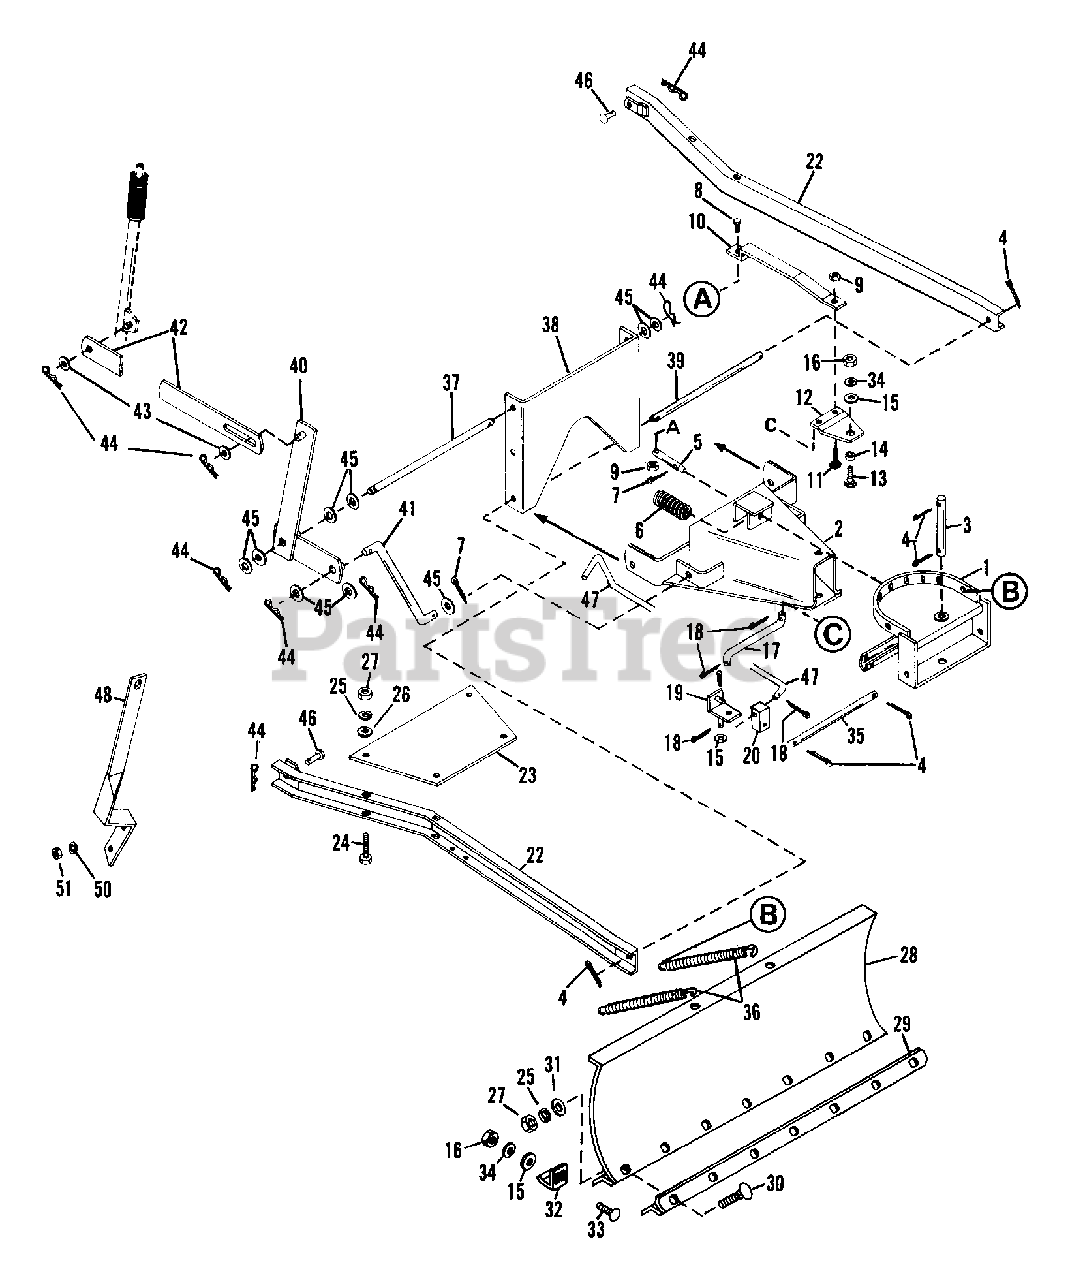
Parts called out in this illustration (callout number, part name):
1	SUPPORT
2	PUSH FRAME
4	PIN-COTR .18X1.0 PL
5	LATCH PIN
6	SG-COMP .080X.85X1.44
7	PIN-COTR .12X1.0 PL
8	BLT-HEX .31-18X1.25 PL GR2
9	NUT-LK .312-18 GR A PL
11	BLT-RDHDSQNK .312-18X.62SHTPL
12	PIVOT PLATE
13	BLT-HEX .38-16X1.00 PL
14	SPACER .406X.749X.162
15	WSHR-FL-STL .438X1.0X.083 PL
16	NUT-HEX .375-16
18	PIN-COTR .12X.75 PL
20	UNIVERSAL BLOCK JOINT
22	CHANNEL
23	STIFFENER PLATE
24	BLT-HEX .31-18X2.50 PL GR5
25	WSHR-LK .312X.097 PL HVY
26	WSHR-FL-STL .323X.625X.062 PL
27	NUT-HEX .312-18
28	WELDMENT, SNOW BLADE
29	WEAR PLATE
30	BLT-RDHDSQNK .31-18X1.00 PL
31	WSHR-FL-STL .38X.875X.083 PL
32	SKID SHOE
33	BLT-RDHDSQNK .38-16X1.0 PL
34	WSHR-LK .375X.094 MED PL
36	SG-TENS .187X1.50X9.94 WLD 40
37	MOUNT ROD
38	PIVOT SUPPORT
39	PIVOT ROD
40	LIFT BELLCRANK
41	LIFT LINK
42	LIFT STRAP
43	WSHR-FL-STL .531X1.062X.095 PL
44	PIN-HAIR INT .09X.188 PL
45	WSHR-FL-STL.656X1.312X.095 PL
46	PIN-CLEV .494X1.25 YWZC
47	CONTROL ROD
48	CONTROL SUPPORT
50	WSHR-LK .312X.097 PL HVY
51	NUT-HEX .312-18
